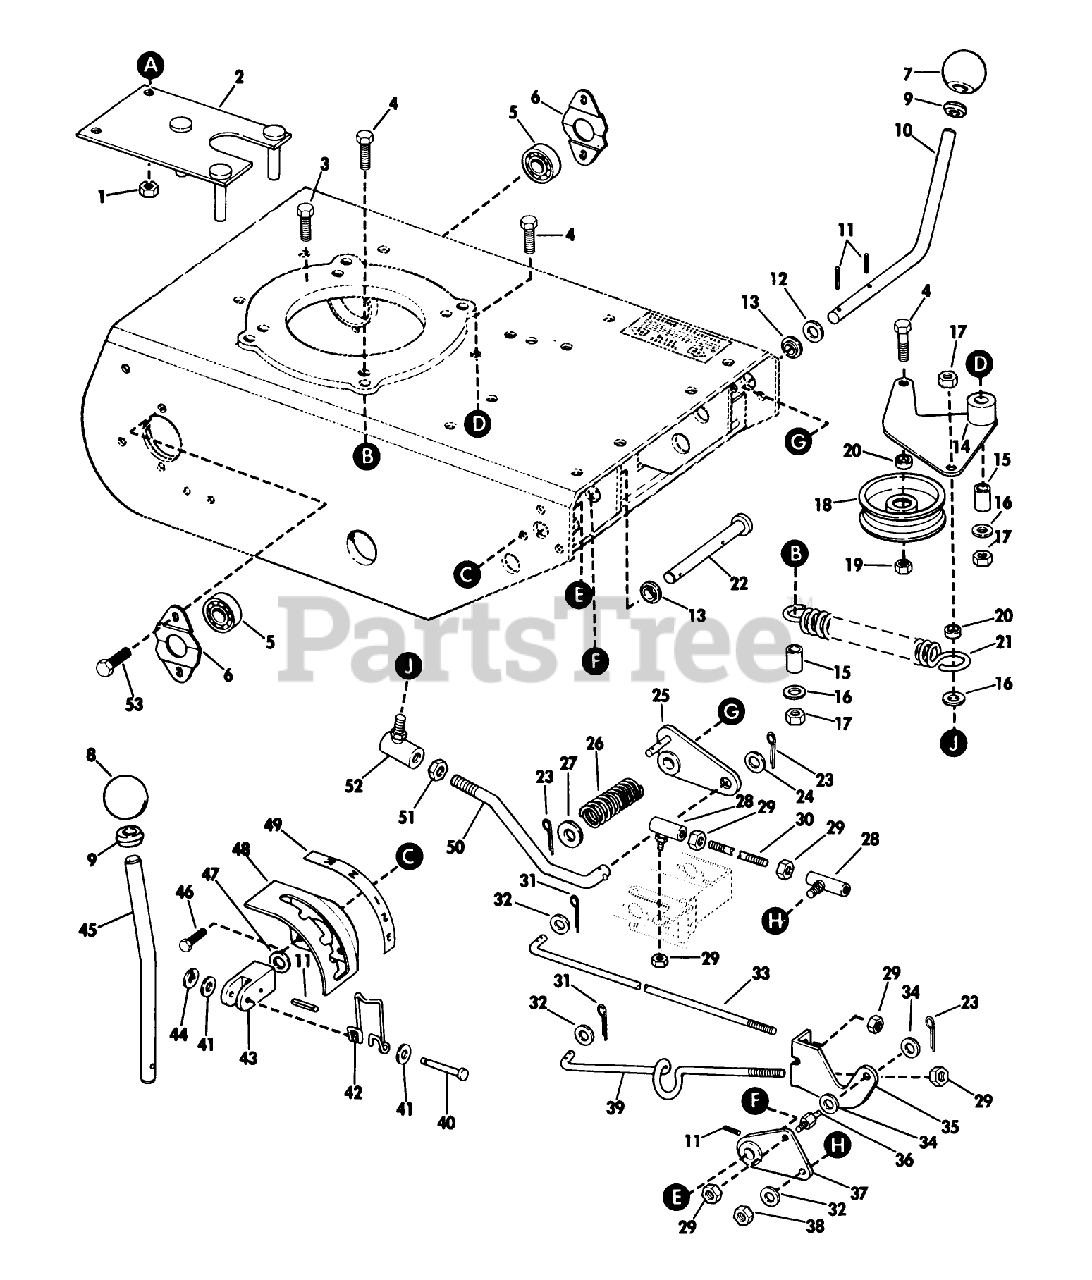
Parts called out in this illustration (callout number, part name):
2	Belt Keeper Assembly
29	STOP NUT
38	STOP NUT
